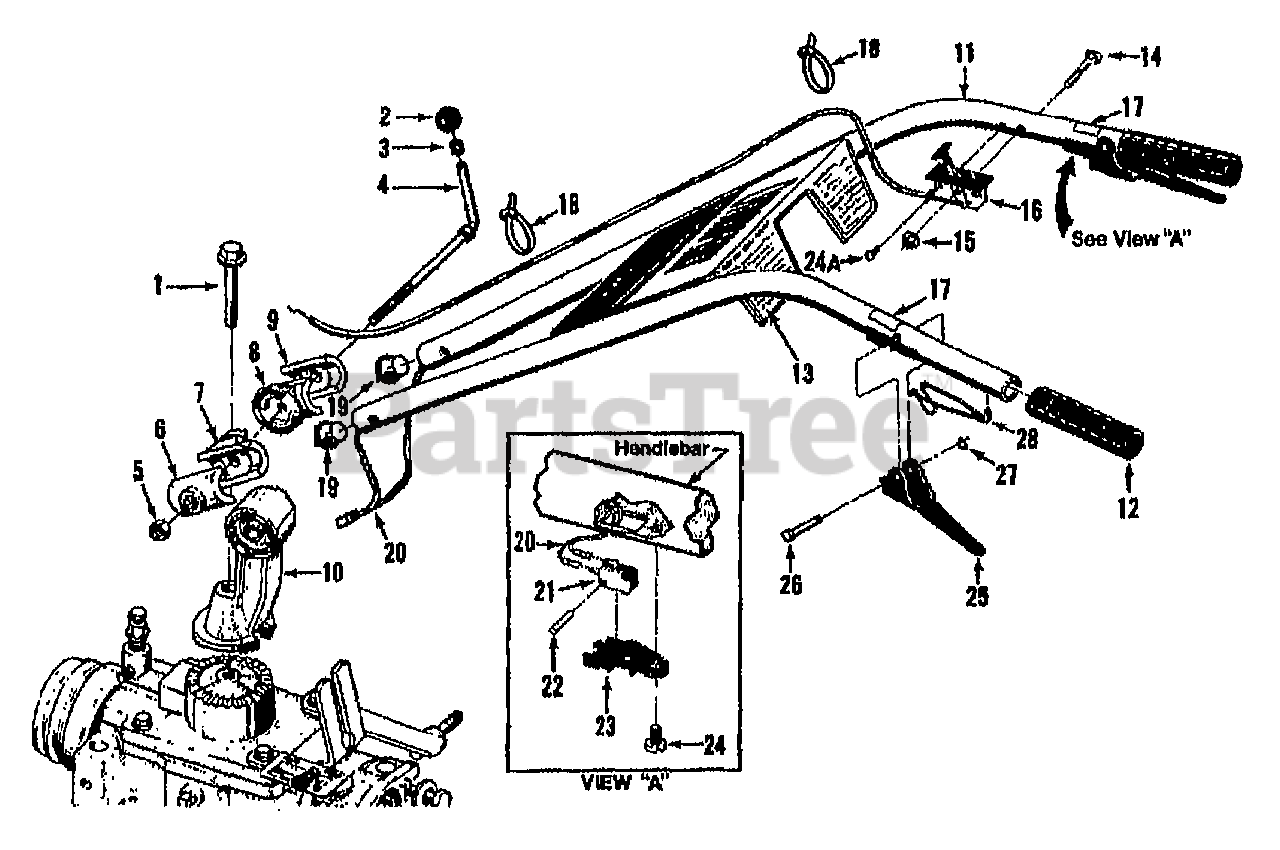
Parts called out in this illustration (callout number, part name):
1	BOLT 1/2-13X3.5 FH GR5
2	KNOB-CONTROL (INCL. 3)
3	RING-TOLERANCE .5325 ID
4	STUD-H/BAR W/NUT & RING (INCL. 2,3 & 5)
5	NUT-HEX JAM 1/2-13
6	CLAMP-LH HORSE 1021-1
7	RATCHET-H/BAR RED 2542-1
8	RATCHET-RH RED HORSE 2542-2
9	CLAMP-RH HORSE 1021-2
10	BASE-H/BAR RED 2534A
11	ASSM-HANDLEBAR W/GRIPS (INCL. 2 OF EA. 12, 17 & 28 AND ONE 13)
12	GRIP-H/BAR SMOOTH
13	DECAL-CONTROL PANEL HORSE
13	DECAL-CONTROL PANEL (11HP)
14	BOLT-CH 1/4-20X2.00 ZP
15	NUT-HF/LK 1/4-20 ZP
16	CABLE-THROTTLE 7 I/C B&S {12068/069/080/081/087}
16	CABLE-THROTTLE 7&8 B&S {12074/075/088/089/090}
16	CABLE-THROTTLE 8HP OPC {12070/071/082/083}
17	DECAL-FWD INTERLOCK
18	TIE-RED
19	RETAINER-HARNESS H/B OPC
20	HARNESS-WIRE OPC HORSE
21	SWITCH-H/B OPC
22	PIN-LK .11X.58 HORSE OPC
23	HOUSING-SWITCH OPC
24	SCR-HW M10-24X.5 STH ZP
24A	SCR-PHS M10-32X.5 STH ZP
25	LEVER-HORSE OPC
26	PIN-PIVOT OPC LEVER
27	RING-KLIP 5304-25
28	SPRING-H/B LEVER
